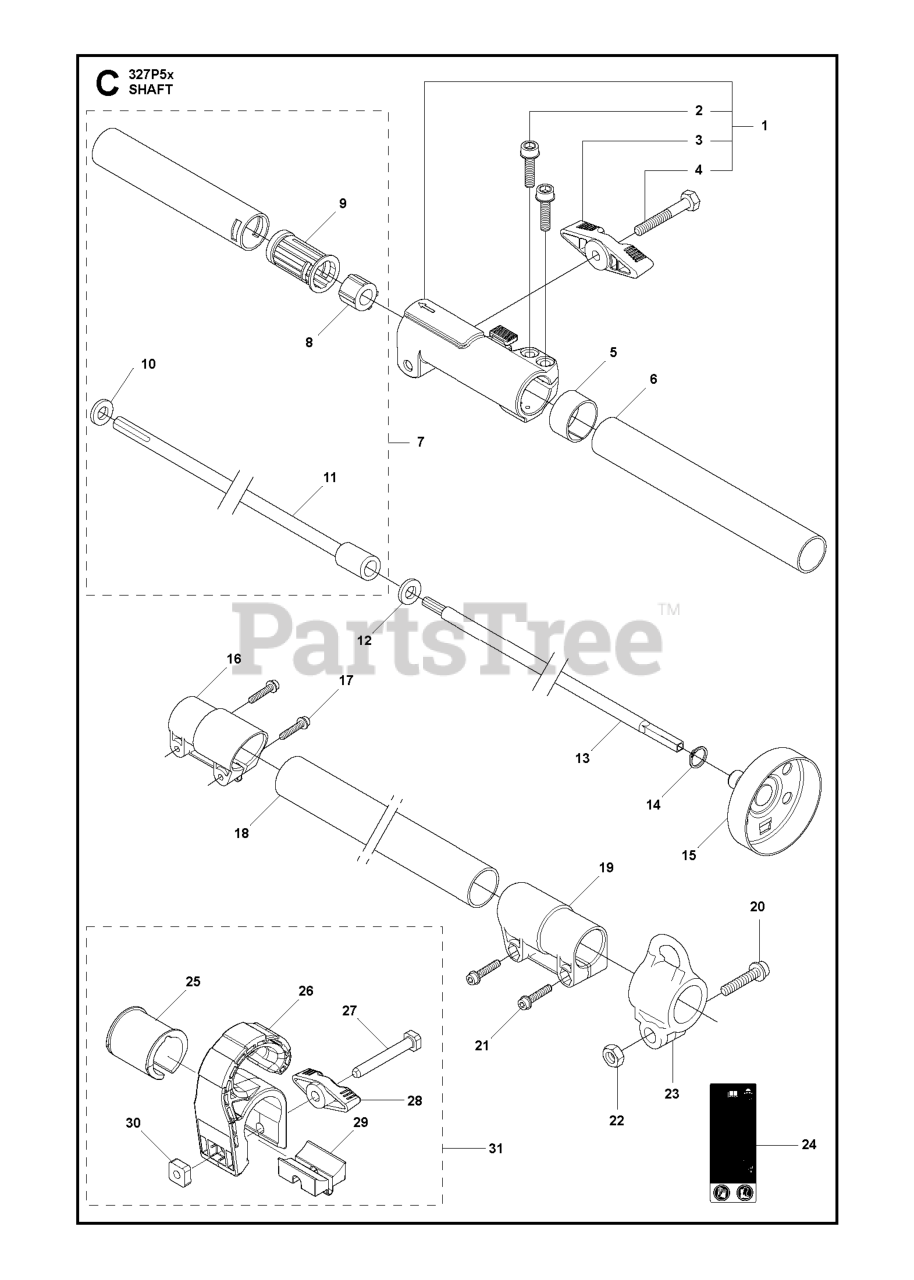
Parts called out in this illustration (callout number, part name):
1	CLAMPING SLEEVE
2	SCREW
6	TUBE
7	TUBE
8	BUSHING
9	PLUG
11	SHAFT
13	DRIVE SHAFT
14	CLUTCH DRUM
14	LOCKING SLEEVE
14	RETAINING RING SGA 10
15	CLUTCH DRUM
16	LOCKING SLEEVE
18	PIPE
19	LOCKING SLEEVE
20	SCREW
23	HARNESS HOLDER
24	DECAL WARNING SPARK ARRESTOR
29	SPACING BLOCK 30
31	ACCESSORY BAG
